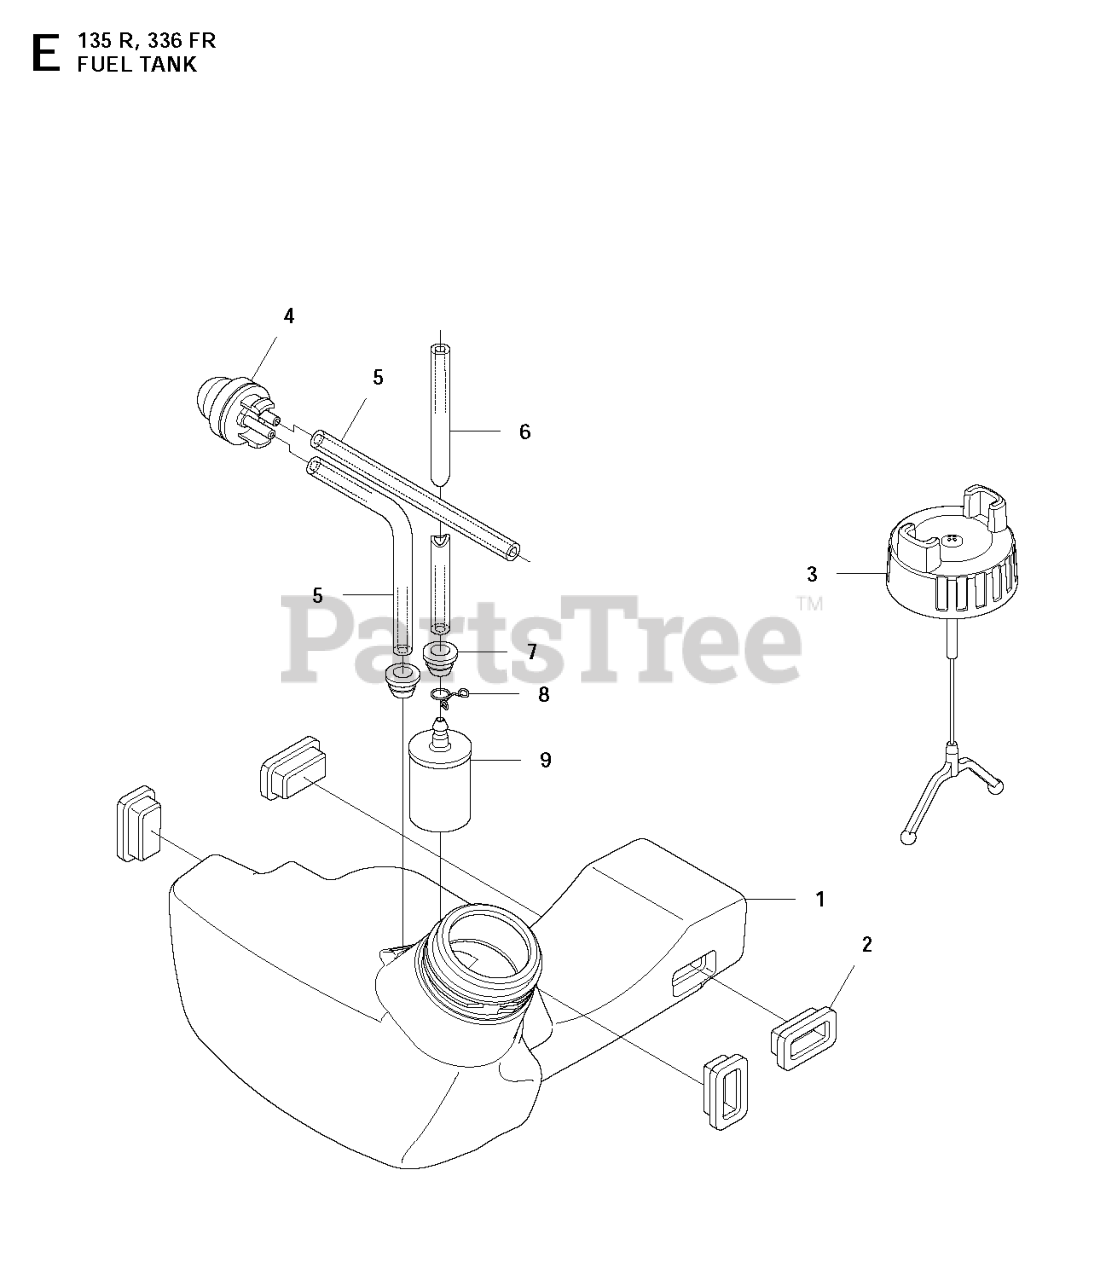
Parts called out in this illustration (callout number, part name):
4	AIR PURGE BUBBLE
7	FUEL TANK BUSHING
9	RP FUEL FILTER
